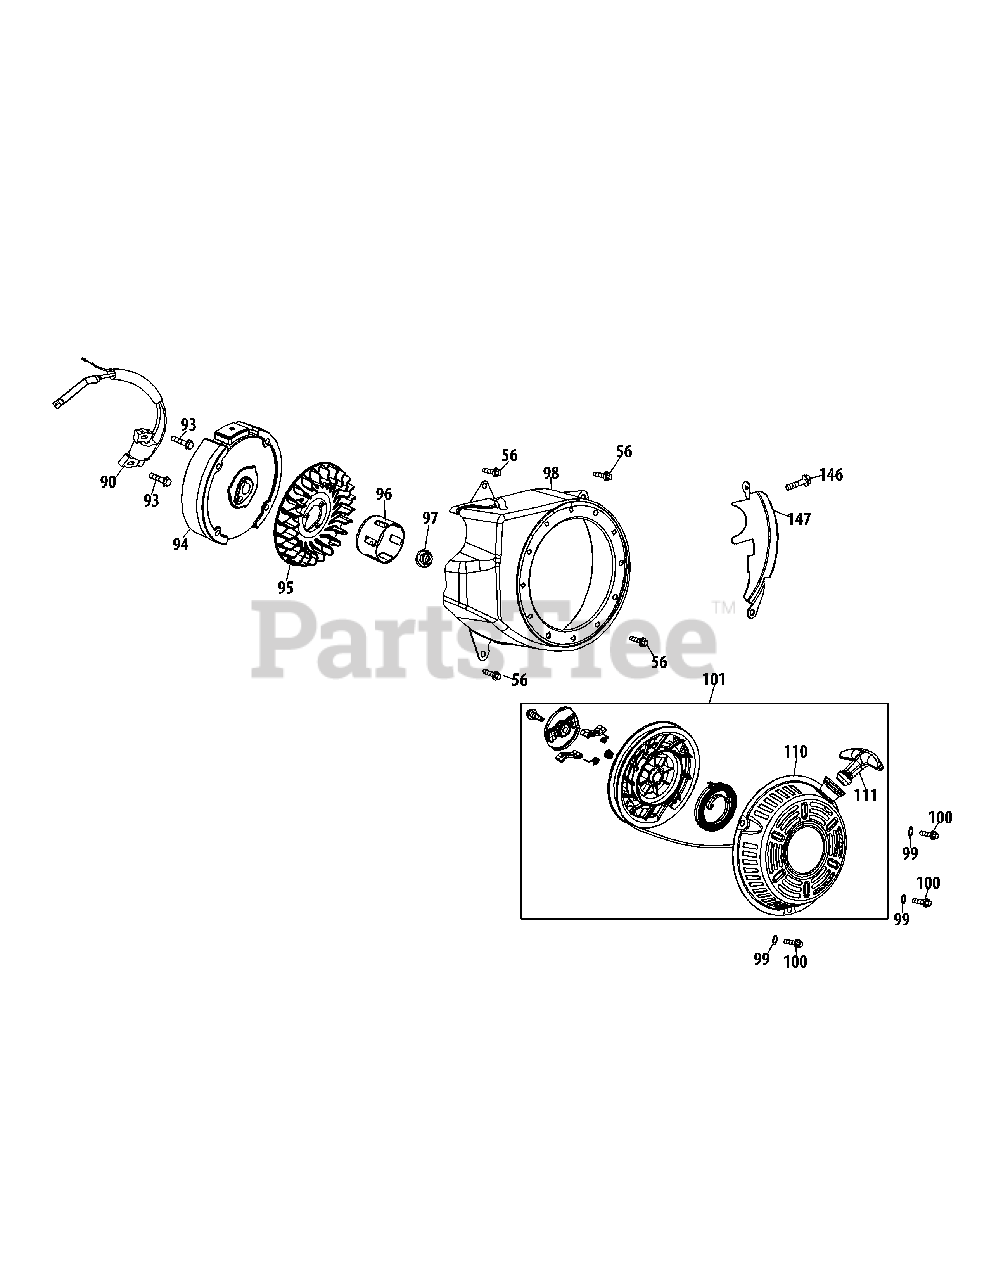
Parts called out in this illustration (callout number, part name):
90	Ignition Coil Assembly
93	Bolt M6×25
95	Cooling Fan
96	Starter Cup
97	Flywheel Nut, M14 X 1.5
98	Blower Housing
99	Gasket ?6
100	Bolt M6×10
101	Recoil Starter Assembly
110	Blower Housing
111	Starter Handle
146	Bolt M6×20
147	Blower Housing Shield
